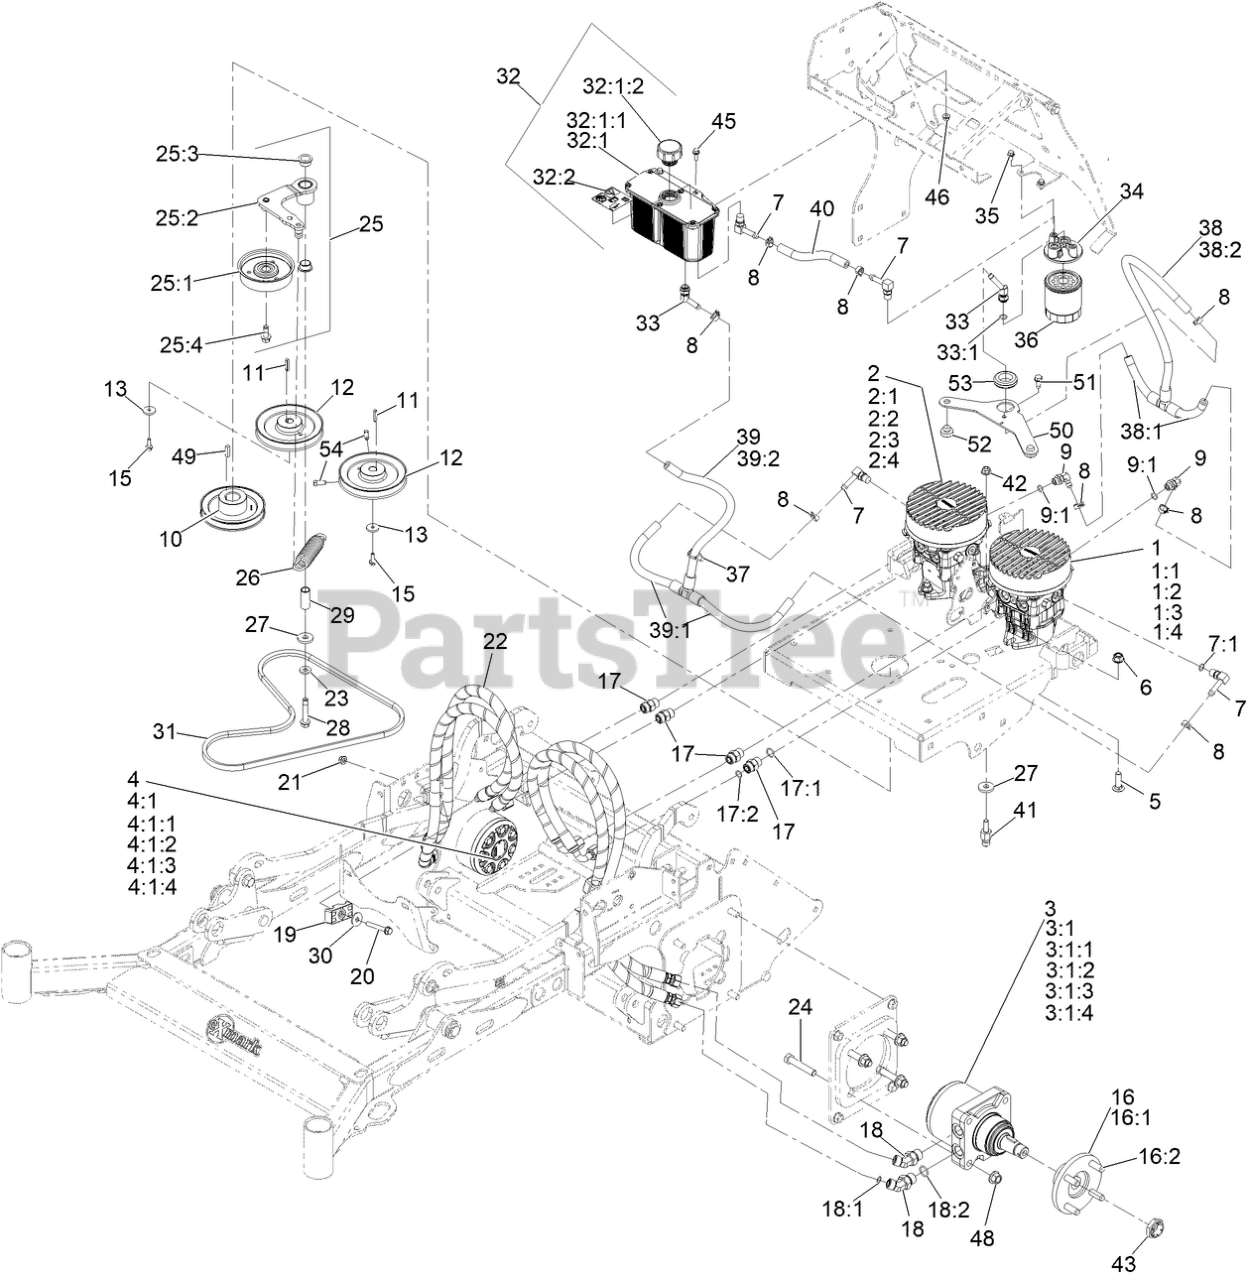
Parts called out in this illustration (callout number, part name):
1	PUMP-12CC LT W/SHOCK VALVE
1:1	KIT, 10CC/12CC PUMP KIT
1:2	SEAL OVERHAUL KIT
1:3	GUARD-PUMP
1:4	PUMP-COOLING
2	PUMP-12CC RT W/SHOCK VALVE
2:1	KIT, 10CC/12CC PUMP KIT
2:2	SEAL OVERHAUL KIT
2:3	GUARD-PUMP
2:4	PUMP-COOLING
3	MOTOR, TL240 LH
3:1	SEAL KIT
4	MOTOR, TL240 RH
4:1	SEAL KIT
5	BOLT-CARR
6	NUT-HF, NI
7	FITTING-ELBOW, 90
7:1	O-RING
8	CLAMP-HOSE
9	FITTING-90 DEG
9:1	O-RING
10	SHEAVE-PUMP, DRIVE
11	KEY, 5MM X 5MM X 29MM
12	SHEAVE-PUMP
13	WASHER-1.00 OD X .25 ID
15	SCREW-HHF
16	WHEEL HUB / STUD ASM
16:1	HUB-WHEEL
16:2	STUD-TYPE, DRIVE
17	FITTING-STRAIGHT
17:1	O-RING
17:2	O-RING
18	Fitting-HYD, 45 DEG
18:1	O-RING
18:2	O-RING
19	CLAMP-TUBE
20	CLAMP-TUBE
21	NUT-HF, NI
22	HOSE ASM-HYD HP
23	WASHER-BELLEVILLE
24	SCREW-HH
25	ASM-PUMP IDLER
25:1	PULLEY-IDLER 4.15 FLAT SINGLE FLNG
25:2	ASM-PUMP IDLER ARM
25:3	BUSHING-FLANGE
25:4	SCREW-HFH
26	SPRING, EXTENSION
28	SCREW-HHF
29	PIVOT, IDLER
31	BELT-COG A 54
32:1	Reservoir-HYD
32:1:1	Cap-Reservoir, HYD
32:2	DECAL-WARNING
33	FITTING-BARBED, 45 DEG
33:1	O-RING
34	HEAD-FILTER
35	SCREW-HHF
36	FILTER-25 MICRON, BI-DIRECTIONAL
37	CLIP-TIE
38	ASM-Hydraulic Lo-Pres
38:1	HOSE, LP HYDRO
38:2	HOSE, LP HYDRO
39	ASM-Hydraulic Lo-Pres
39:1	HOSE, LP HYDRO
39:2	HOSE, LP HYDRO
40	Hose, LP Hydro
41	PIN-SPRING, ANCHOR
42	NUT-HF, NI
43	LOCKNUT
45	SCREW-HHF
46	NUT-HHF
48	Nut-Lock 1/2-13
50	PLATE-HOLD DOWN
51	SCREW-THD ROLL, HWH
52	BUMPER-RUBBER
53	GROMMET
54	SCREW-SET, SQH
